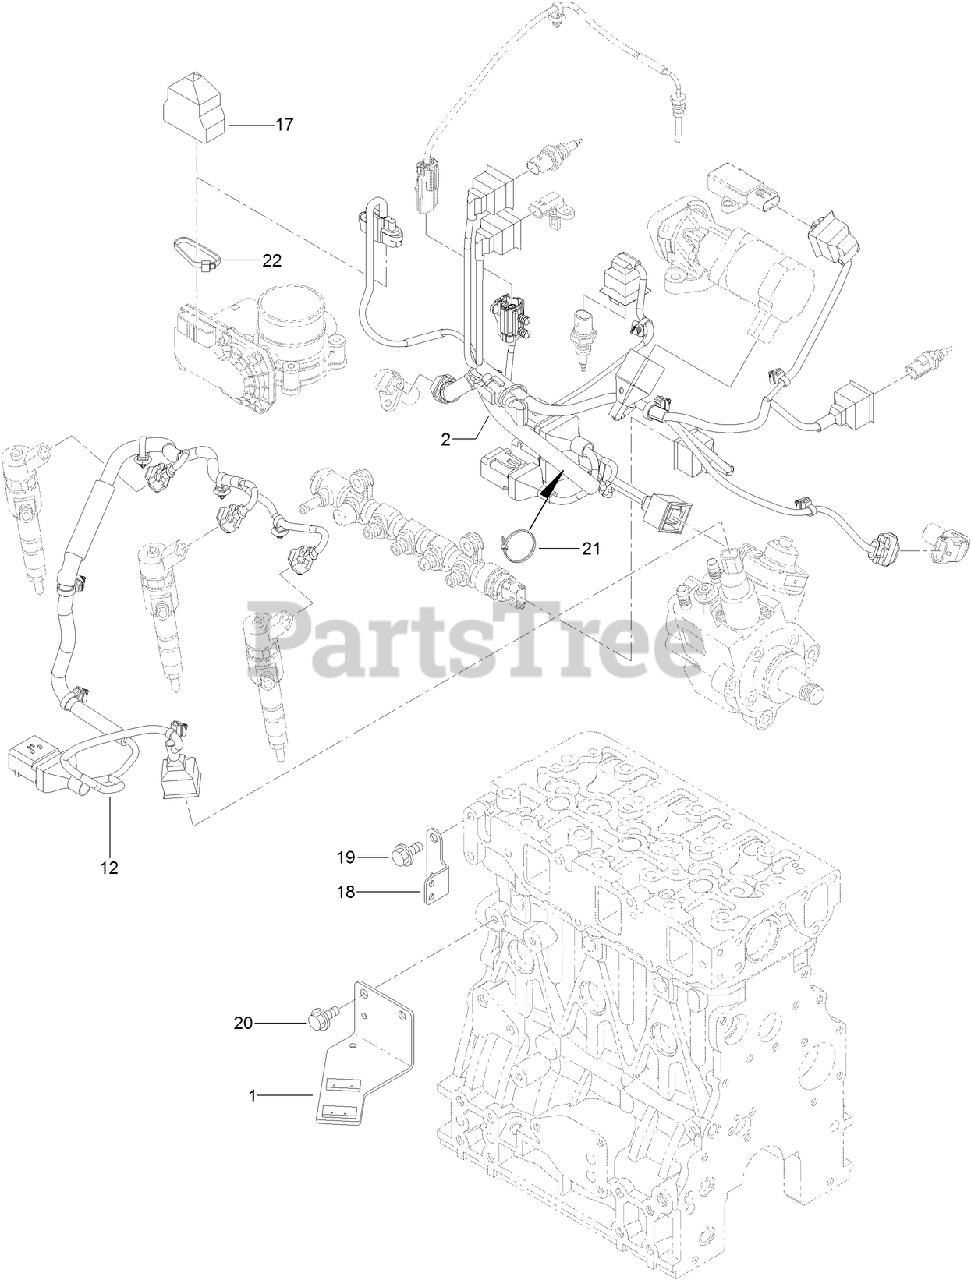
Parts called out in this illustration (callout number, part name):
1	BRACKET-CONNECTOR
2	HARNESS B-ENGINE, E C O
12	HARNESS
17	BOOT-TYPE, CAP
18	BRACKET-HARNESS
